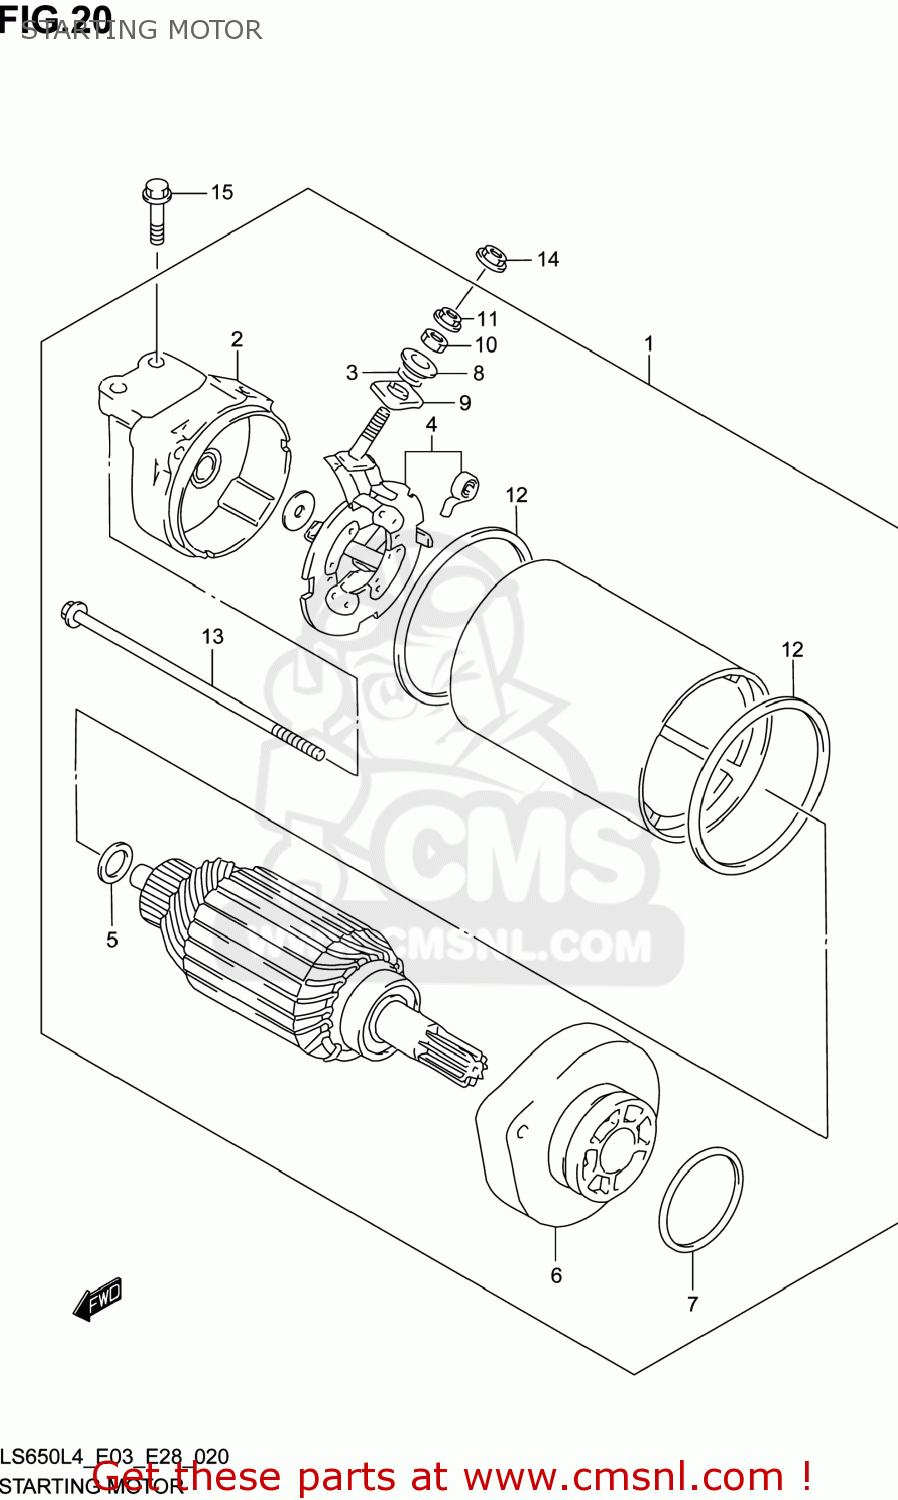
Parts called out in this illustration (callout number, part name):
1	MOTOR ASSY,STARTING
2	FRAME ASSY
3	O RING
4	HOLDER SET,BRUSH
5	SHIM SET,STARTING MOTOR
6	HOUSING ASSY
7	O RING
8	BUSHING
9	BUSHING
10	NUT
11	NUT
12	O RING
13	BOLT
14	NUT
15	BOLT(6X20)
